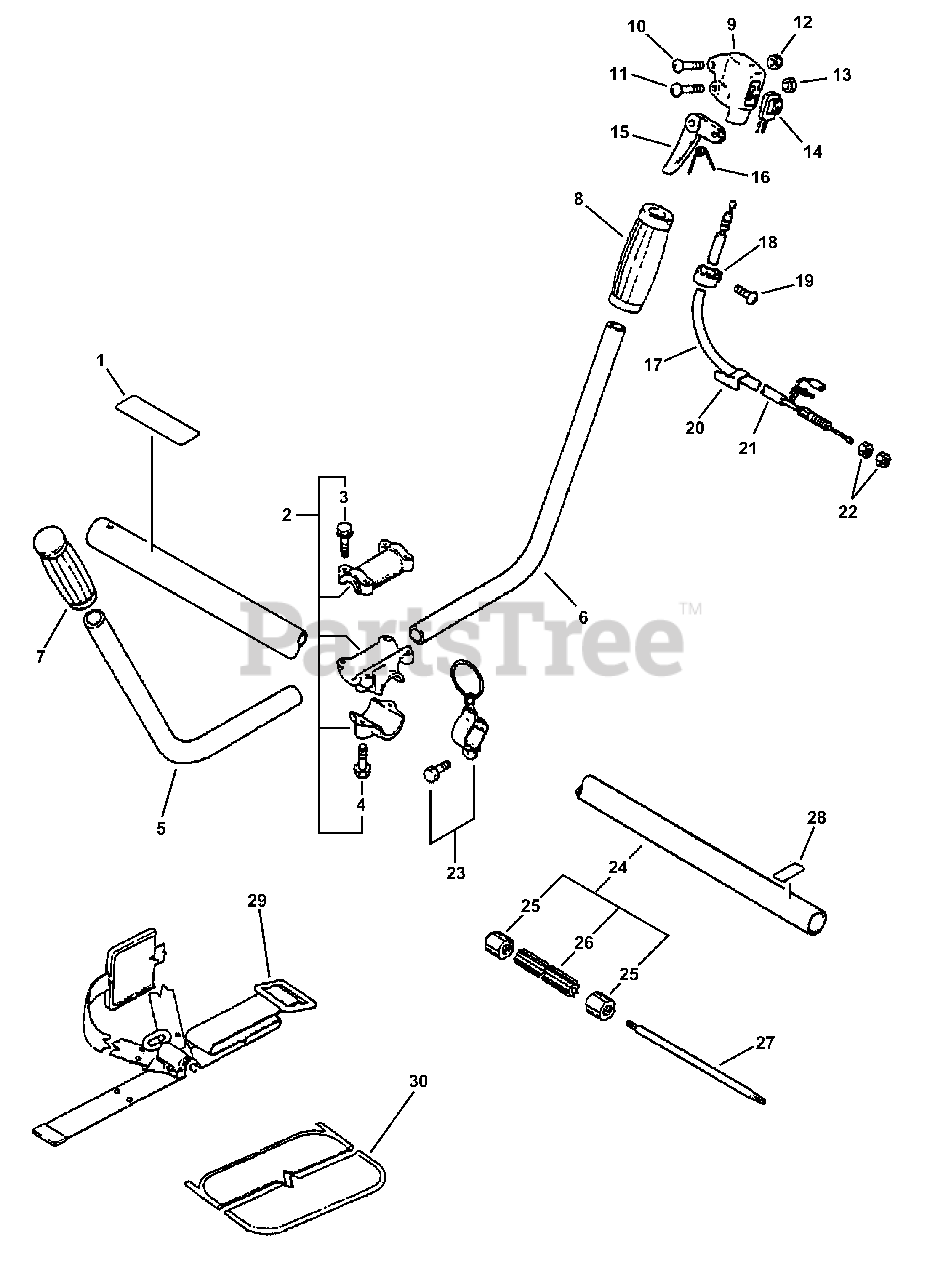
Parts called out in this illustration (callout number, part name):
1	LABEL - CAUTION
2	HANDLE BRACKET KIT
3	BOLT - 5X25
4	BOLT - 6X30
5	HANDLE, FRONT - LEFT
7	GRIP, HANDLE - LEFT
8	GRIP, HANDLE
9	BRACKET, THROTTLE
10	SCREW - 5X25
11	SCREW - 5X30
12	LOCKNUT - 5
14	IGNITION SWITCH ASSY
15	TRIGGER, THROTTLE
16	SPRING, TRIGGER
17	CABLE, THROTTLE
19	SCREW - 5X10
21	TUBE
22	LOCKNUT - 6
23	HOOK
24	MAIN PIPE ASSY
26	LINER - FLEXIBLE
27	DRIVESHAFT - FLEXIBLE
28	LABEL - ALIGNMENT
29	SHOULDER STRAP ASSY
30	CUSHION
